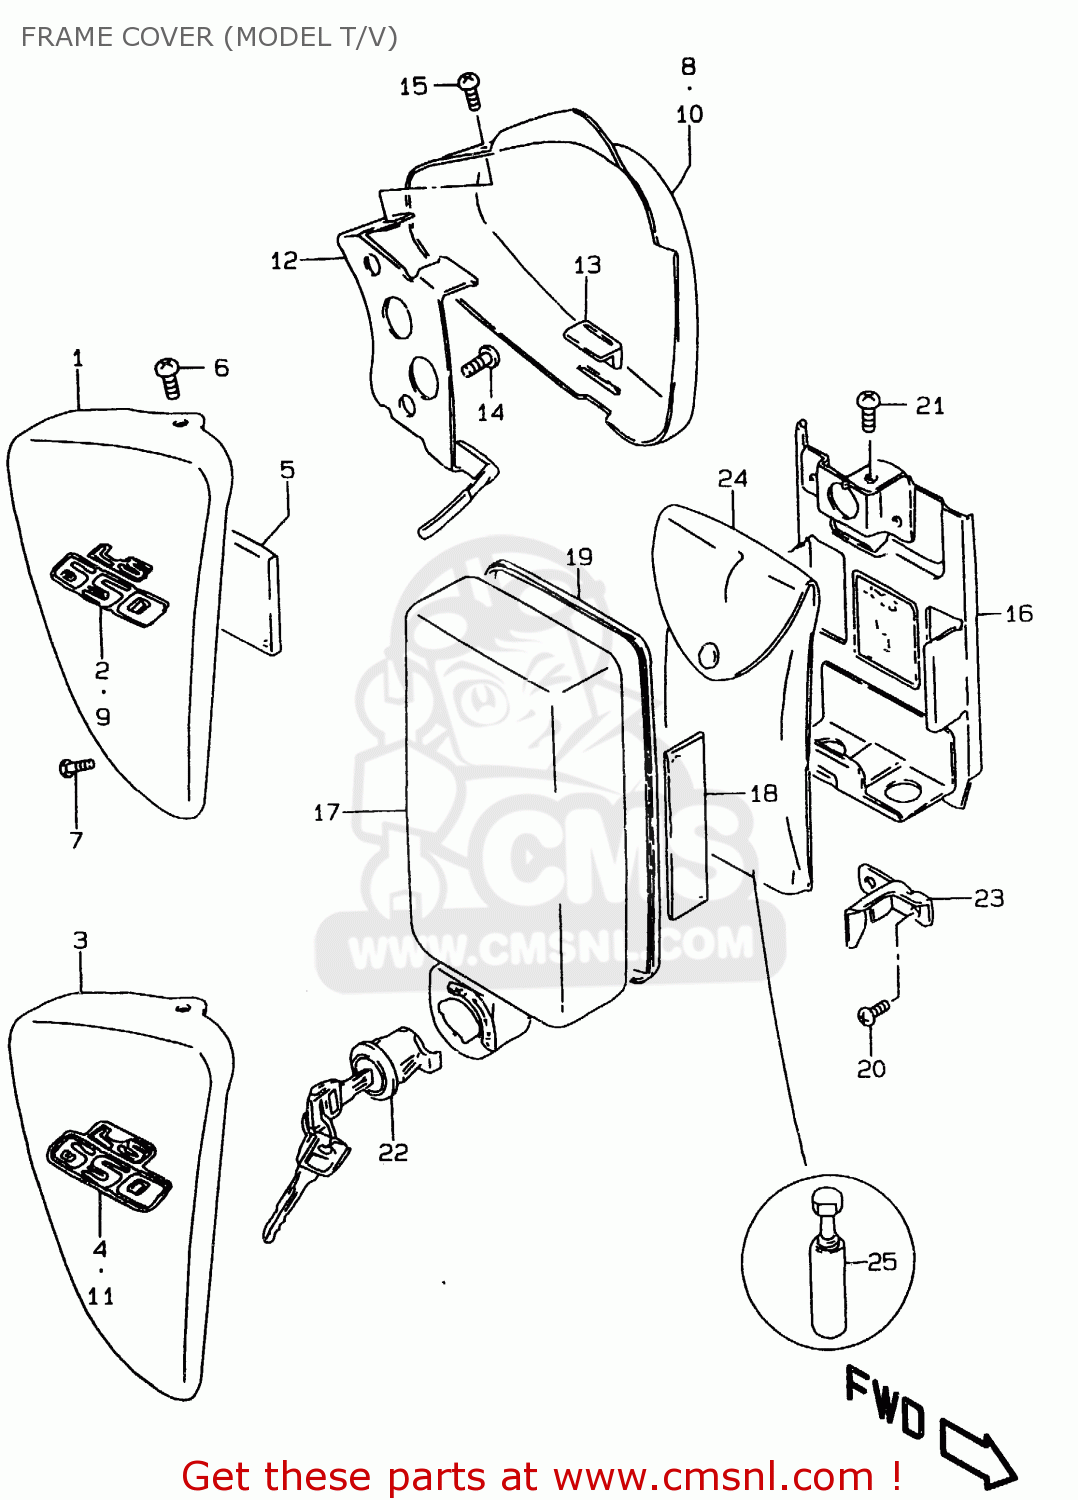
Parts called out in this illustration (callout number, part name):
1	COVER ASSY,FRAME,R(BLACK)
2	EMBLEM
3	COVER, FRAME RH (GRAY)
4	EMBLEM,FRAME COVER
5	PAD
6	SCREW
7	SCREW
8	COVER ASSY,FRAME,L(BLACK)
9	EMBLEM
10	COVER ASSY,FRAME,L(GRAY)
11	EMBLEM,FRAME COVER
12	BRACKET,FRAME COVER,L
13	CUSHION,FRAME COVER
14	SCREW
15	SCREW
16	HOLDER,TOOL
17	COVER COMP,TOOL HOLDER
18	PROTECTOR(80X80X2)
19	MOLDING
20	SCREW
21	SCREW
22	LOCK SET,TOOL HOLDER
23	PLATE,TOOL HOLDER LOCK
24	TOOL ASSY
25	GAUGE ASSY,TENSION
